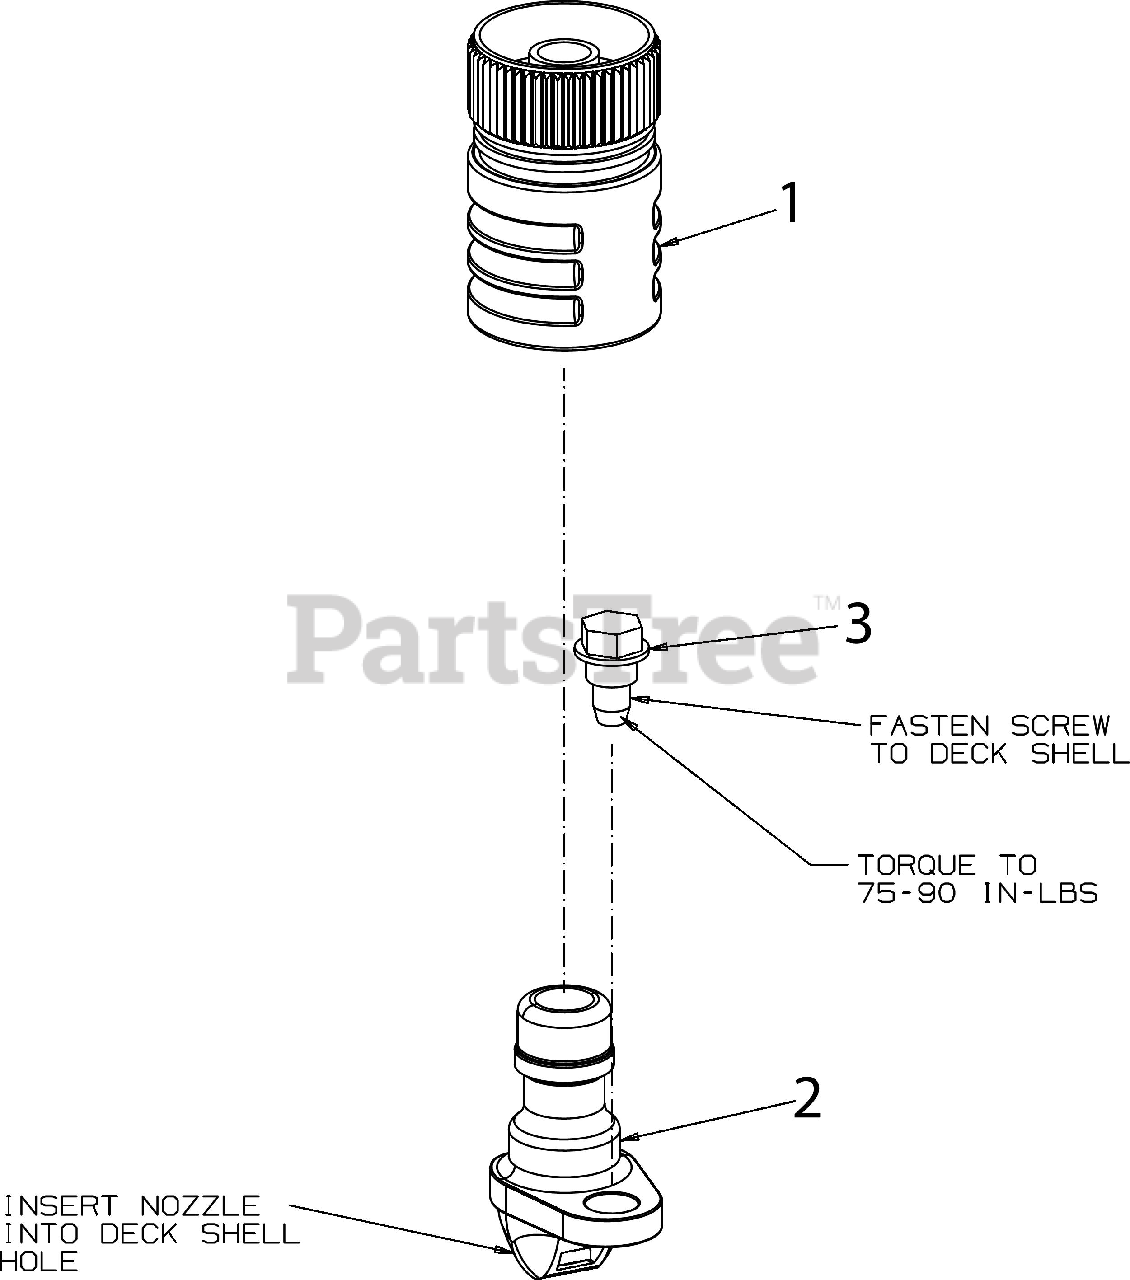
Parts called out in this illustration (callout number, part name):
1	WATER NOZZLE
2	DECK WASH NOZZLE
3	SHOULDER SCREW 1/4-20 x .50
